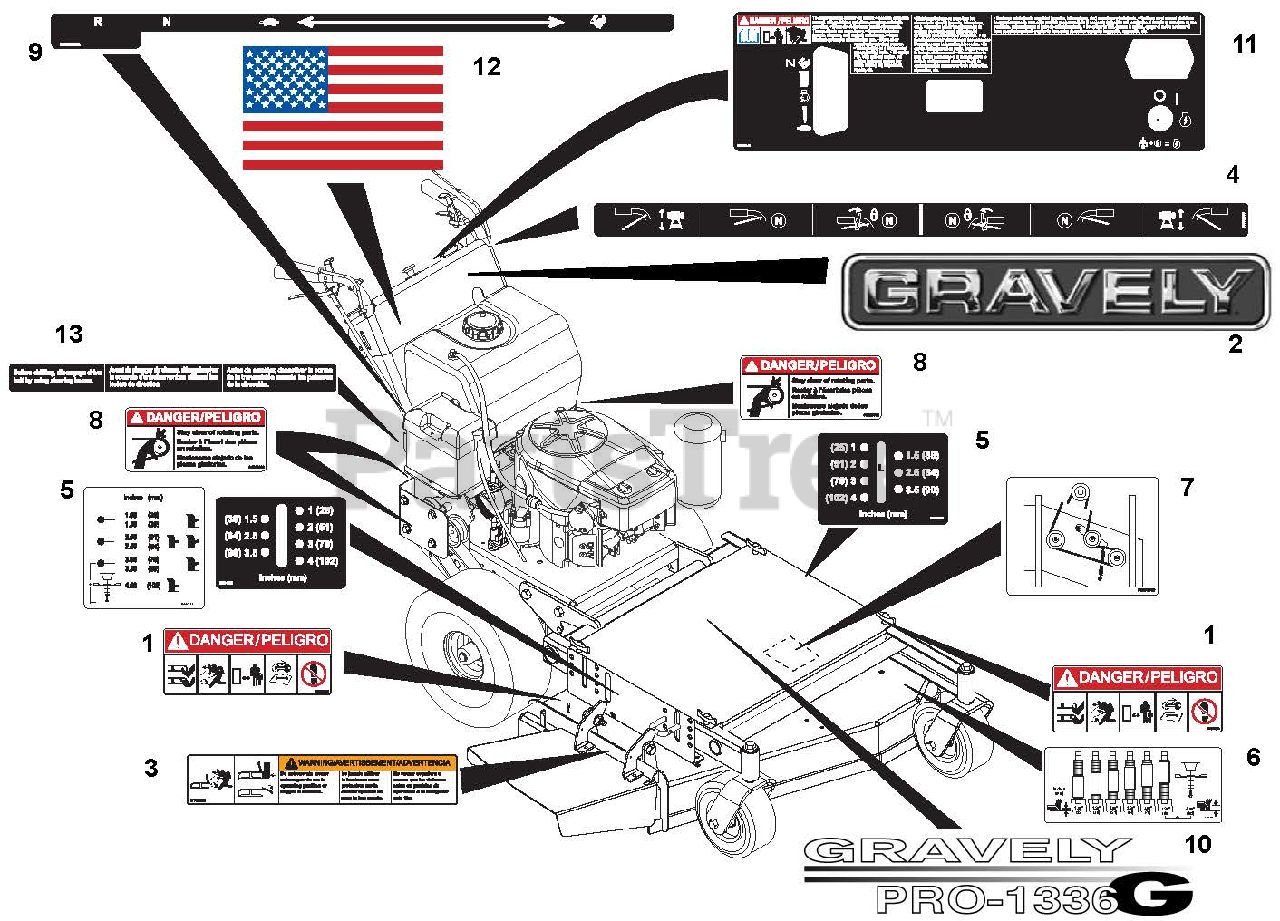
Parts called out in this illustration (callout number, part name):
1	Decal, Mower Pan Head Danger
2	Decal- 15" Gravely Logo
3	Decal, Warning
4	Decal, Steer Levers
4	Decal-Steer Levers-Gear-Pro Steer
5	Decal-Height of Cut-Fixed- Right Hand
5	Decal-Height of Cut-Fixed- Left Hand
5	Decal-Height of Cut-Rear-1334
6	Decal-Height of Cut-Front-1334
7	Decal-Belt Diagram-2 Spindle
7	Decal-Belt Diagram-3 Spindle
7	Decal-Belt Diagram
8	Decal-Danger-Belt Rotating
9	Decal-Shift Lever
10	Decal-Pro 1336G
10	Decal-Pro 1332G
10	Decal-Pro 1548G
10	Decal-Pro 1334G
11	Decal, Control GR15
11	Decal, Control GR15-Pro Steer
12	Decal, American Flag
13	Decal, Declutch
